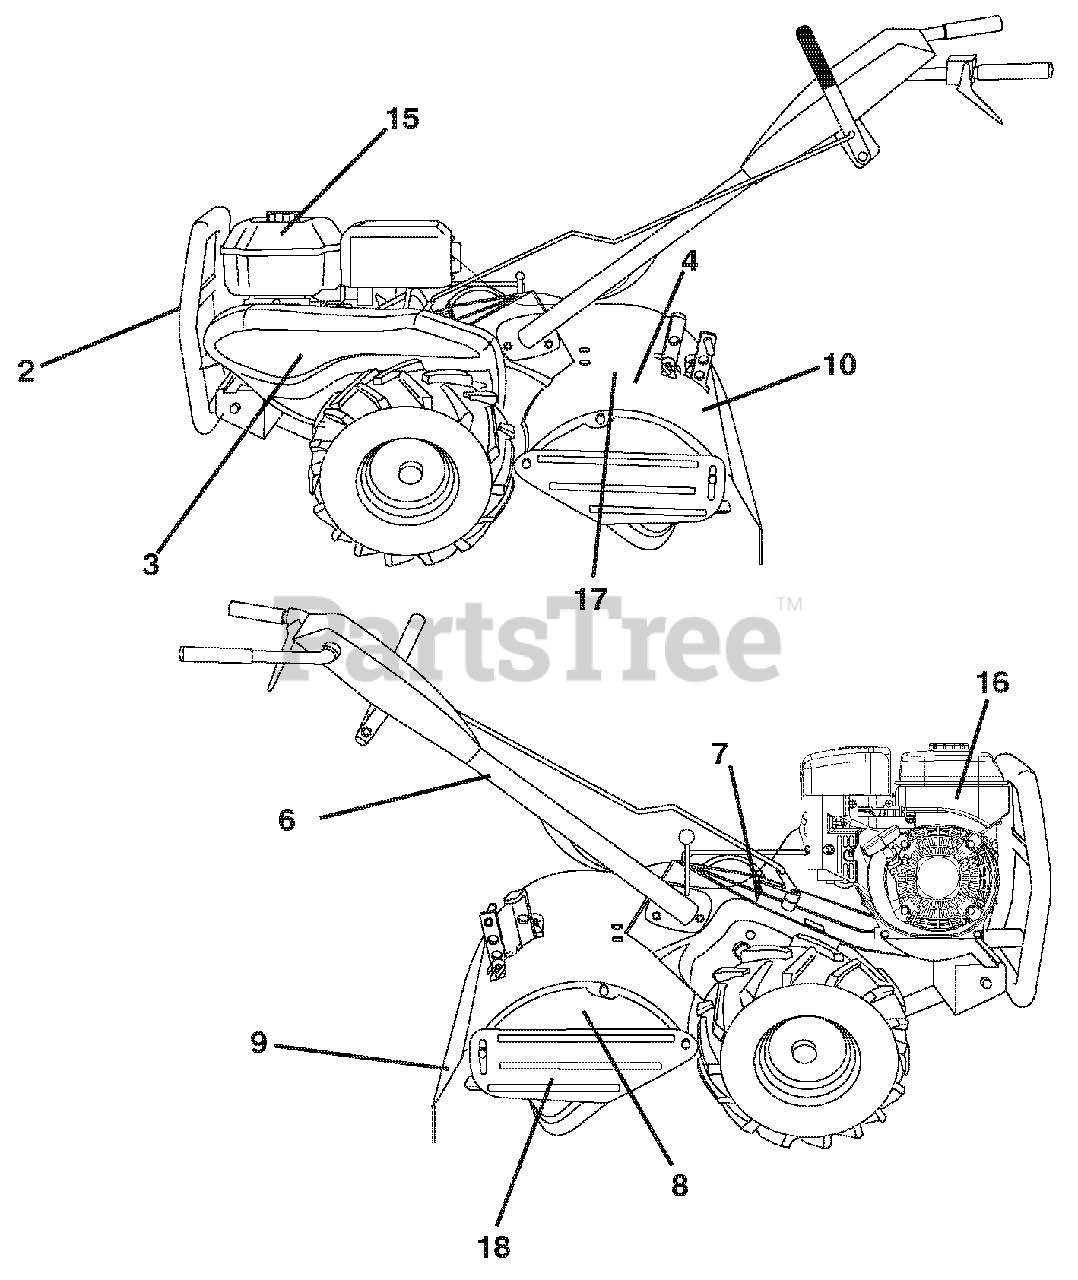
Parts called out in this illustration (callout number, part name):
2	Decal, Subaru Tine Shield
3	Decal, Belt Guard
4	Decal, Tine Shield Forward
6	Decal, Hand Placement
7	Decal, Shift Indicator
8	Decal, Flag
9	Decal, Warning, DRT
10	Decal, Tine Shield DRT REV
15	DECAL, ETHANOL
16	Decal, Warning Spark Arrester
17	Decal, Top Dual
18	Decal, Side
